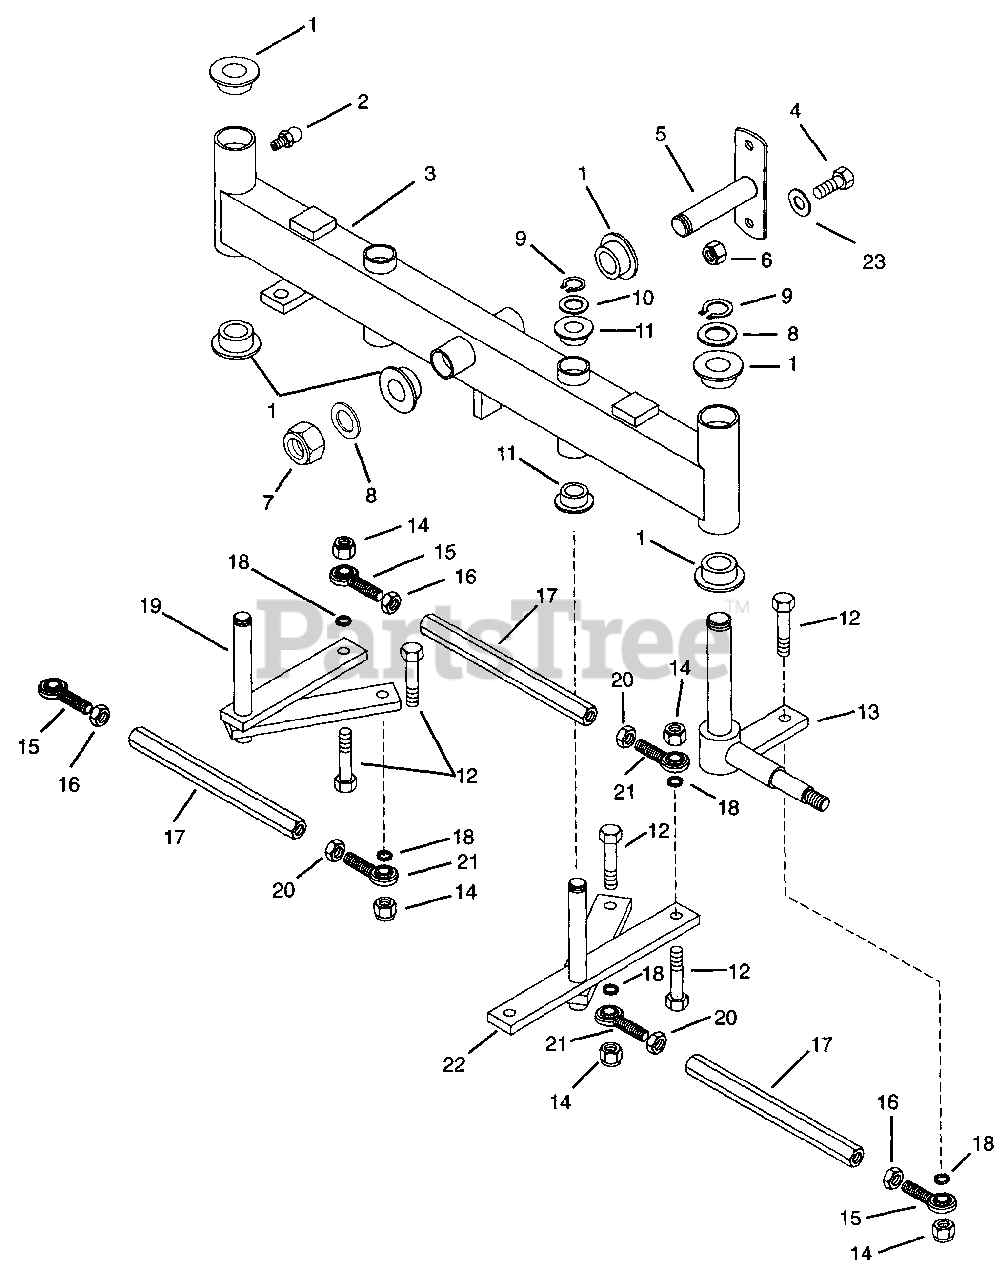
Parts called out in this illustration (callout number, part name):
1	Bushing-Flange 1.020 x 1.385 x .75 x 1.75
2	Fitting-Lube .25-28 x .256
3	Weldment, Axle
4	Bolt-Hex .38-16 x 1.00 Grade 5
5	Weldment, Axle Pin
6	Nut-Locking-Center .38-16
7	Nut-Locking 1.0-14
8	Washer-Flat-Steel 1.010 X 1.505 X .062
9	Ring-Retaining-External .689 x .077
10	Bearing-Needle-Thrust .752 x 1.24 x .031
11	Bushing-Flange .762 x 1.0 x .580 x 1.48
12	Bolt-Hex .50-13 x 2.00 Grade 5
13	Weldment, Kingpin Left Hand
13	Weldment, Kingpin Right Hand
14	Nut-Locking-Center .62-11
15	Assembly, Rod End
16	Nut-Jam .50-20 Grade 2
17	Rod, Tie
18	Spacer .520 x .625 x .125
19	Weldment, Steering Idler
20	Nut-Jam .50-20 Left Hand Grade 2
21	Assembly, Rod End Left Hand
22	Weldment, Steering Arm
23	Washer-Flat-Steel .281 x .620 x .065
